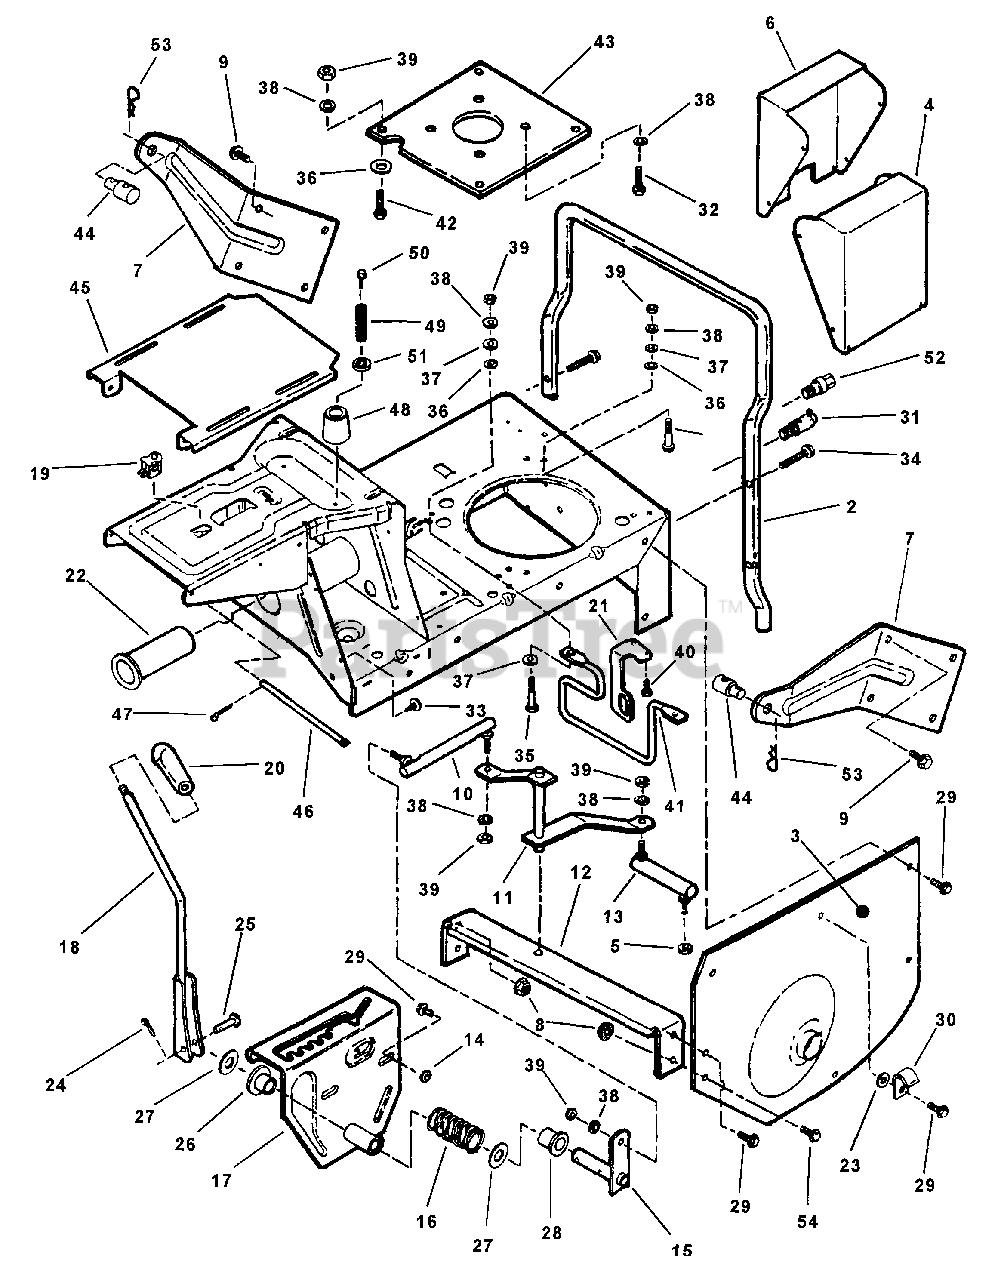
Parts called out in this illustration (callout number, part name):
2	BUMPER, Rear
3	FENDER, Left Hand
4	COVER, Battery
5	NUT, 5/16-24 Hex Flange Lock
6	COVER, Switch
7	WING, Rear
8	NUT, 5/16-18 Hex Flange Lock, Grade 5
9	SCREW, 5/16-18 x 3/4" Hex Washer Self-Tap
10	LINK, Shift (Long)
11	ARM, Shift (Weldment)
12	CROSS BRACE
13	LINK, Shift (Short)
14	NUT, 5/16-18 Hex
15	ARM, Shift Handle (Weldment)
16	SPRING, Shift Handle
17	DETENT, Shift (Weldment)
18	HANDLE, Shift (Weldment)
19	SWITCH, Seat
20	KNOB, Shift Handle
21	BRACKET, Switch
22	BUSHING, Pilot
23	WASHER, 5/16" Internal Tooth Lock
24	COTTER-PIN, 3/32 x 3/4"
25	PIN, 1/4 x 1-3/4" Tapered Clevis
26	BUSHING, Nylon
27	WASHER, Thrust
28	BUSHING, Nylon
29	SCREW, 5/16-18 x 5/8" Hex Washer Self-Tap
30	CLIP, Wire
31	DRAIN, Oil (1/4 Turn)
32	BOLT, M8-1.25 x 25mm Hex Head Self-Tap
33	FASTENER, 1/4 x 3/4" Ratchet
34	SCREW, 5/16-18 x 1-1/2" Hex Washer Self-Tap
35	SCREW, 5/16-24 x 1-3/4" Hex Head Cap, Grade 5
36	RETAINER, 5/16" Bolt
37	WASHER, 5/16" Flat
38	WASHER, 5/16" Split Lock
39	NUT, 5/16-24 Hex, Grade 5
40	SCREW, #10-32 x 1/4" Hex Washer Self-Tap
41	GUIDE, Belt
42	SCREW, 5/16-24 x 1" Hex Head Cap, Grade 5
43	PLATE, Engine
44	SWIVEL
45	PLATE, Seat
46	PIN, Hinge
47	COTTER-PIN, 1/16 x 3/4"
48	CUSHION
49	SPRING, Seat (Operator Presence Control)
50	SCREW, 1/4-20 x 5/8" Self-Tapping, Truss Head, Torx
51	WASHER, 1/4" I.D. Flat
52	DRAIN, Oil (Short)
53	HAIRPIN, 3/32 x 1-1/2"
54	SCREW, 5/16-18 x 3/4" Hex Head Cap, Grade 2
